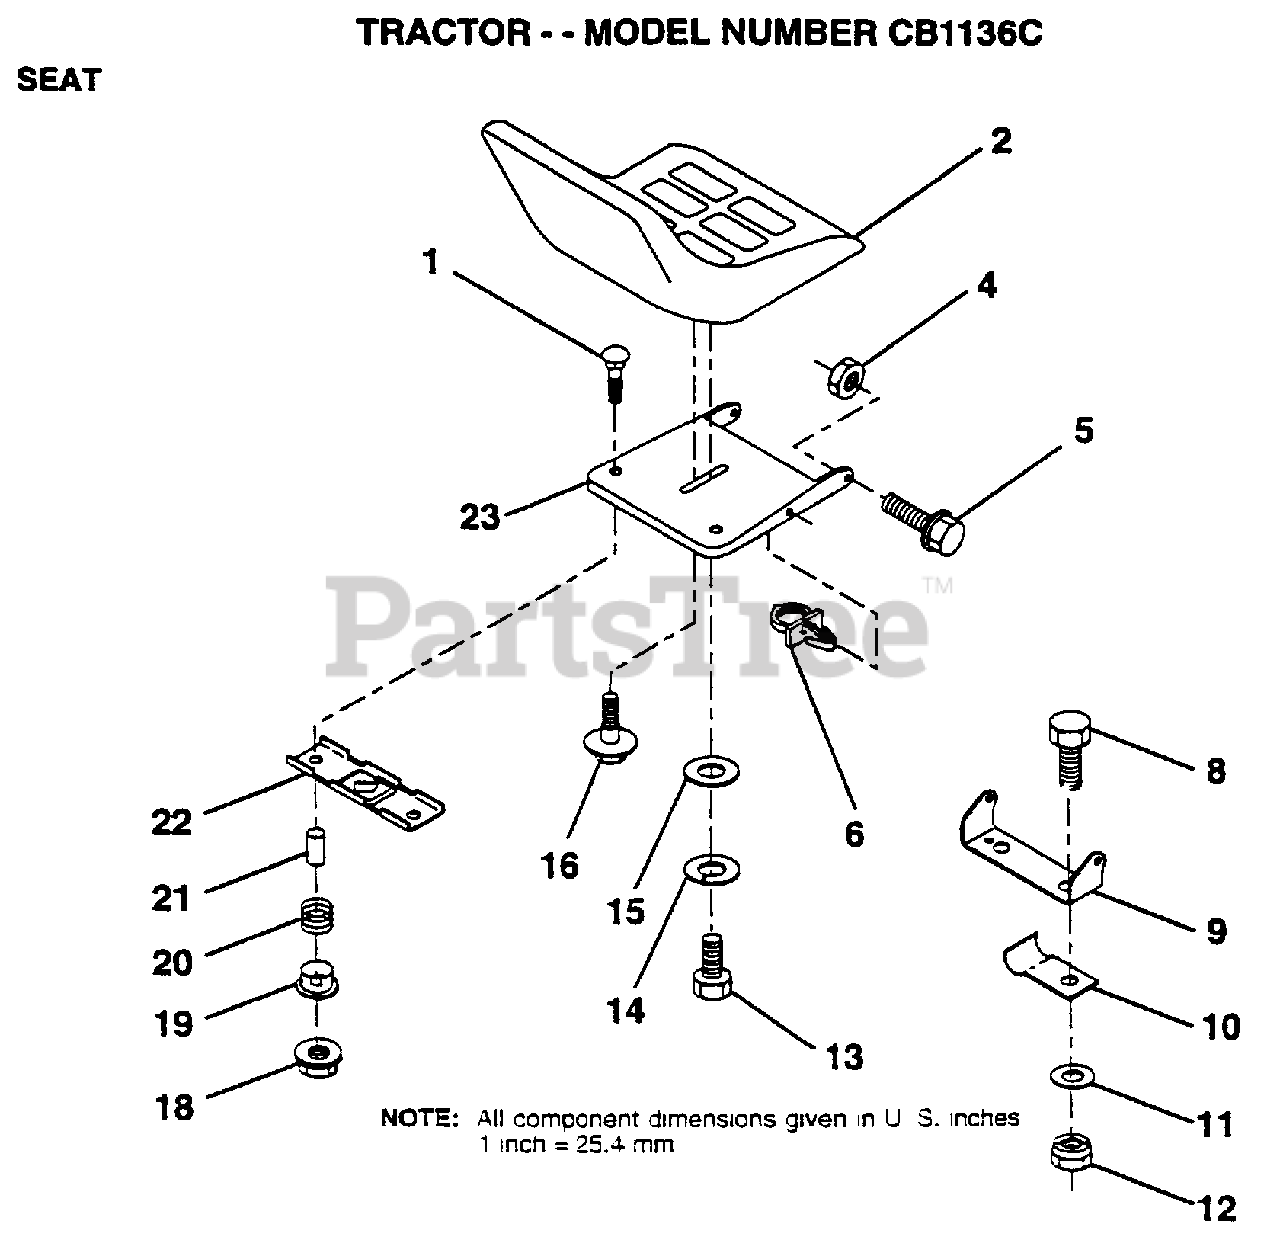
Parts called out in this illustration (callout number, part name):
5	BOLT.SHLD.5/16-18
6	CLIP.PUSH-IN.HING
8	BOLT
9	BRACKET PVT SEAT
10	"CLIP,INSULATOR"
11	WASHER
12	NUT
13	BOLT
14	LOCKWASHER
15	WASHER
16	"BOLT,SHOULDER"
19	BUSHING
20	SPRING
22	BRKT SWITCH
